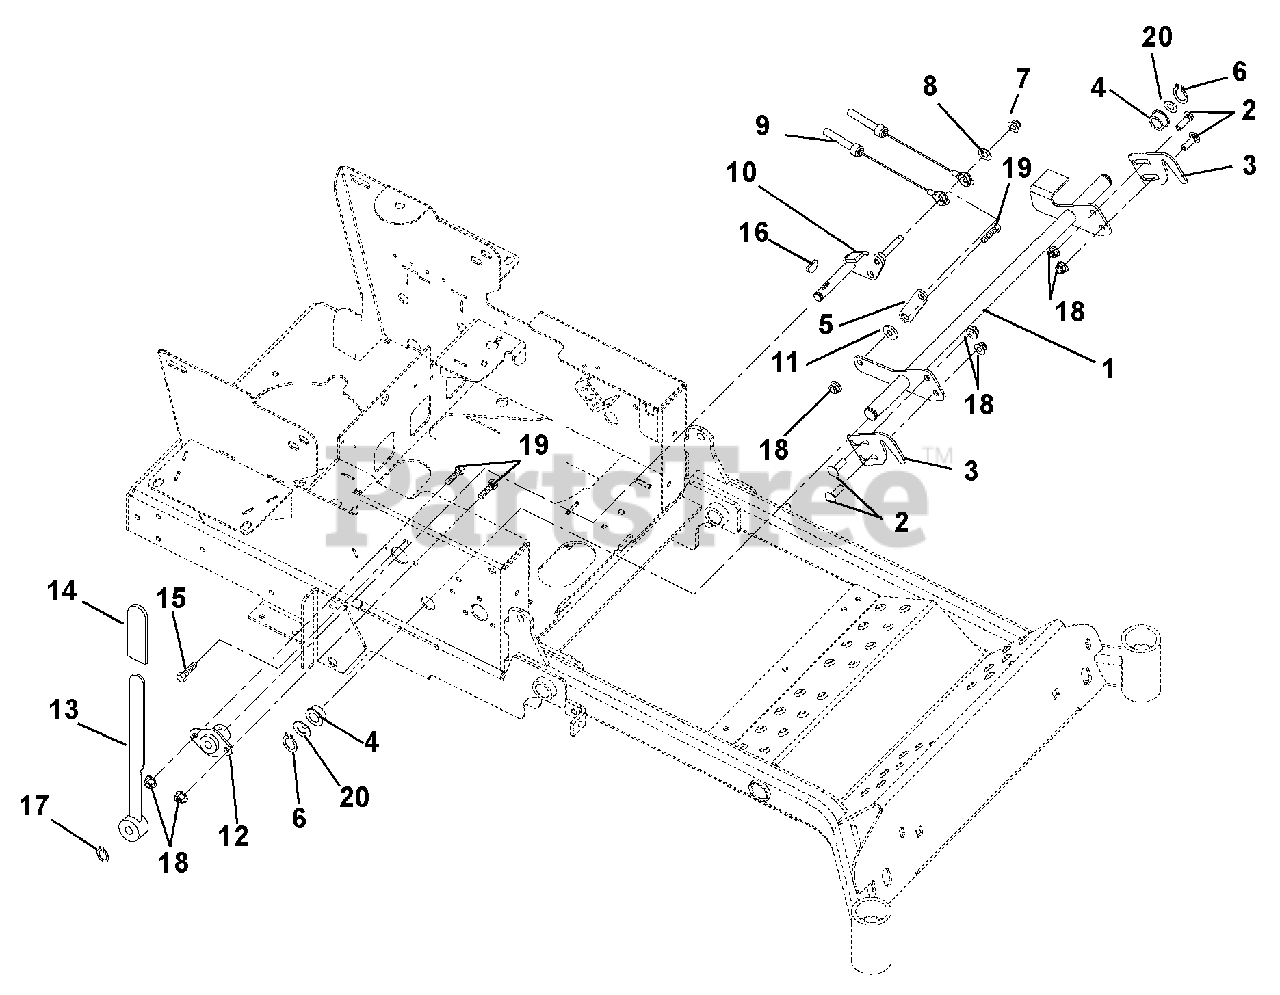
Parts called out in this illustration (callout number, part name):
1	WMT, NEUTRAL INTERLOCK
2	@BLT-RDHDSQNK .31-18X1.00 G5YZ
3	NEUTRAL LOCK LATCH - BLACK
4	BSHG-FLG .750X1.000X.625X1.250
5	PLATE, NEUTRAL INTERLOCK
6	RG-RTNG-EXT .689X.078
7	NUT-PUSH .312
8	@WSHR-FL-STL.344X.688X.065YWZC
9	CABLE, BRAKE ACTUATING
10	WMT, PARK BRAKE ARM
11	BSHG, FLG .325X.499X.26X.88
12	BUSHING, FLANGED
13	WMT - PARKING BRAKE ARM
14	GRIP, PARKING BRAKE (YELLOW)
15	@SCR-TAP .38-16X1.00 HWH TR YZ
16	KEY-WDRF .13X.63 HRD#5
17	RG-RTNG-EXT .500X.050 (SNAP)
18	@NUT-LK-NYL-FLG .31-18 YWZC
19	@BLT-HEX .31-18X1.00 GR5 YWZC
20	WSHR-FL-STL .812X1.370X.10 YWZ
